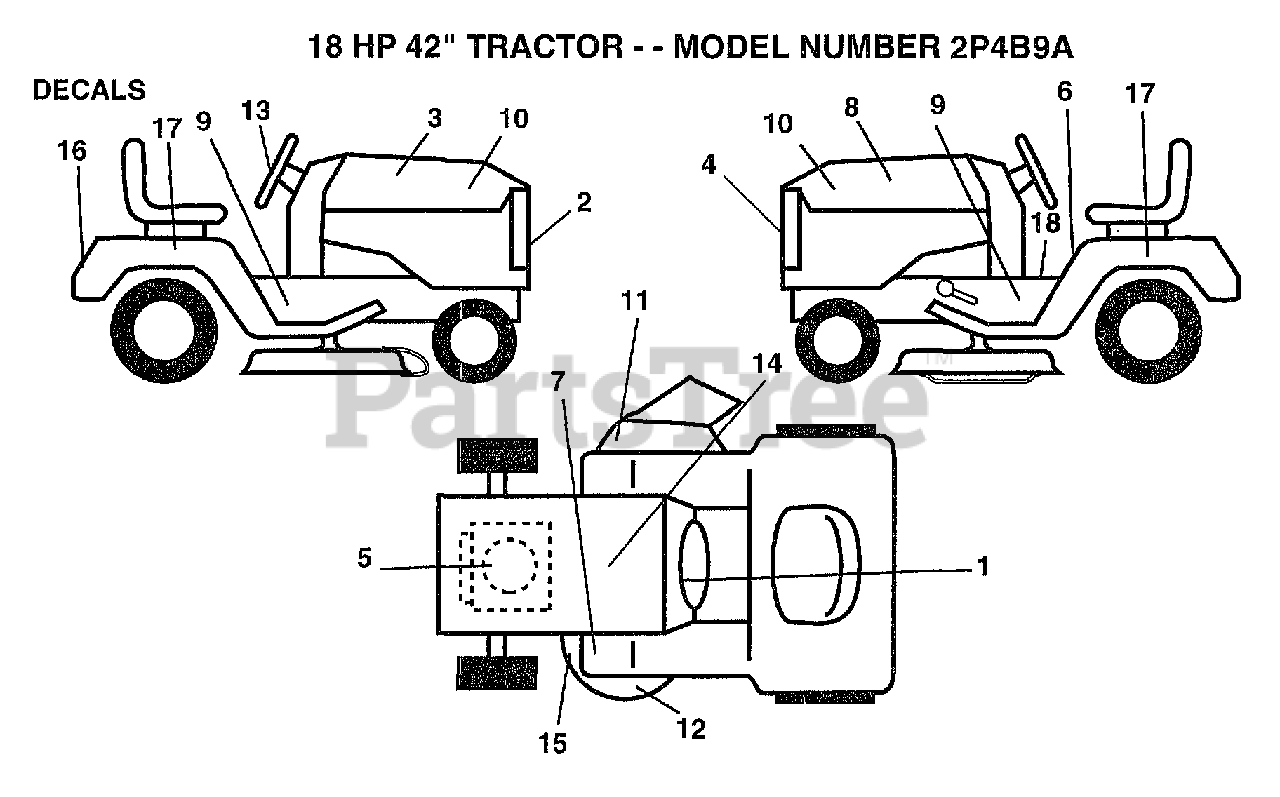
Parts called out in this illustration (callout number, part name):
1	DECAL.DASH.INSTR.
2	GRILL DECAL
3	DECAL HOOD RH RLY
5	DECAL.ENG.272757
6	DECAL CAUTION
7	DECAL T
8	DECAL HOOD LH RLY
10	DECAL.HOOD.INSERT
11	"DECAL, WARNING"
13	"DECAL,STR WHL"
14	DECAL
15	DECAL.V.BELT
16	FENDER DECAL
17	DECAL.FEND.QUICKS
18	DECAL BRAK PARK
